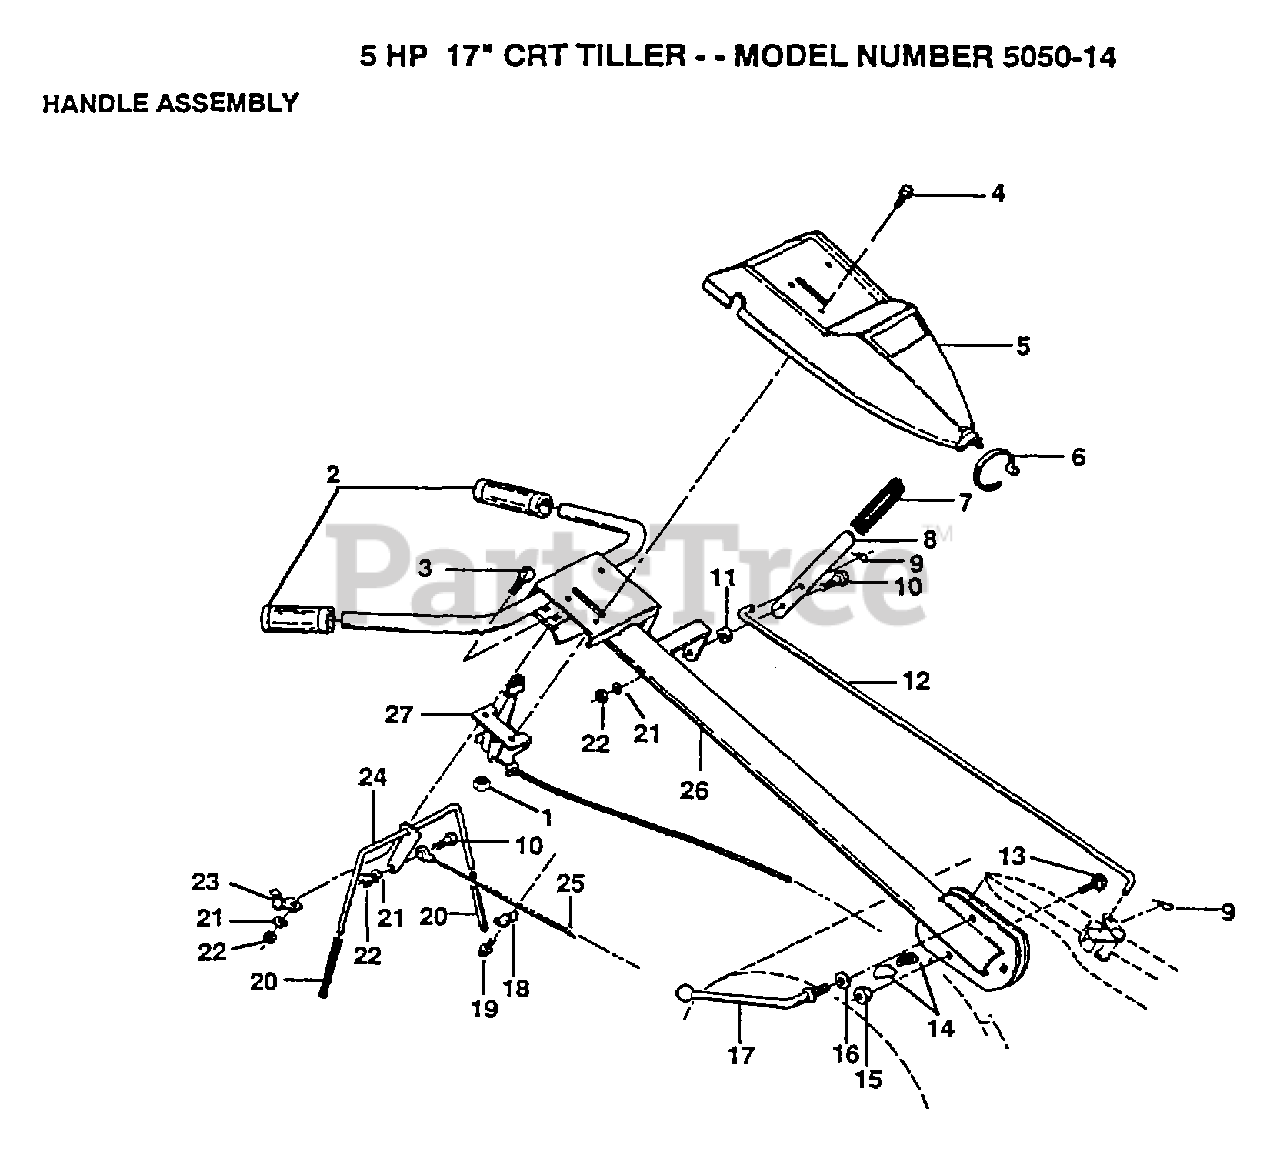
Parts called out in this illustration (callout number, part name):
3	BOLT
4	SCREW
5	"PANEL,CONT TI"
6	TIE CABLE CRT
7	GRIP T
8	SHIFT HANDLE CRT
9	RETAINER M
10	SHOULDER BOLT ST
11	GROMMET CRT
12	SHIFT ROD CRT
13	BOLT D
14	LOCK CRT
16	WASHER CRT
17	LEVER LOCK CRT
18	CONDIUT CLIP T
20	GRIP BAR CRT
21	LOCKWASHER
24	"ASSY CONTROL, BAR"
25	CABLE.CLUTCH.CRT
27	"CONT,THROTTLE"
